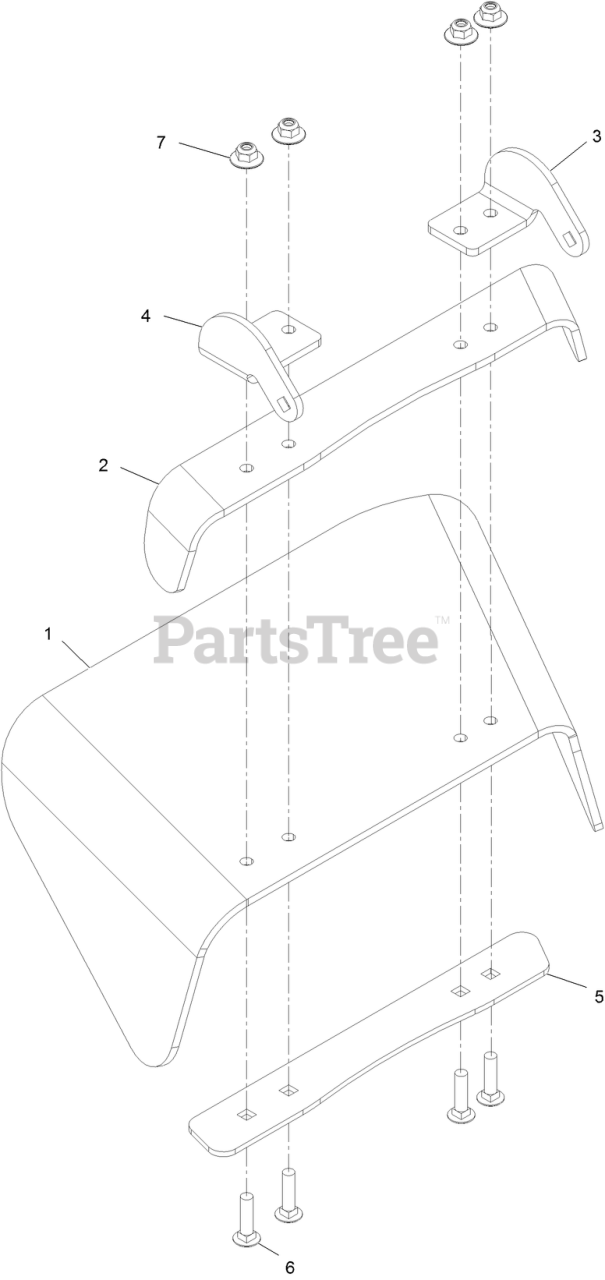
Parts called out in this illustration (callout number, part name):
1	DEFLECTOR-RUBBER
2	BRACKET-TOP DEFLECTOR
3	BRACKET-DEFLECTOR
4	BRACKET-DEFLECTOR
5	STRAP-BOTTOM DEFLECTOR
6	SCREW-CARR
7	NUT-FLANGE, NI
